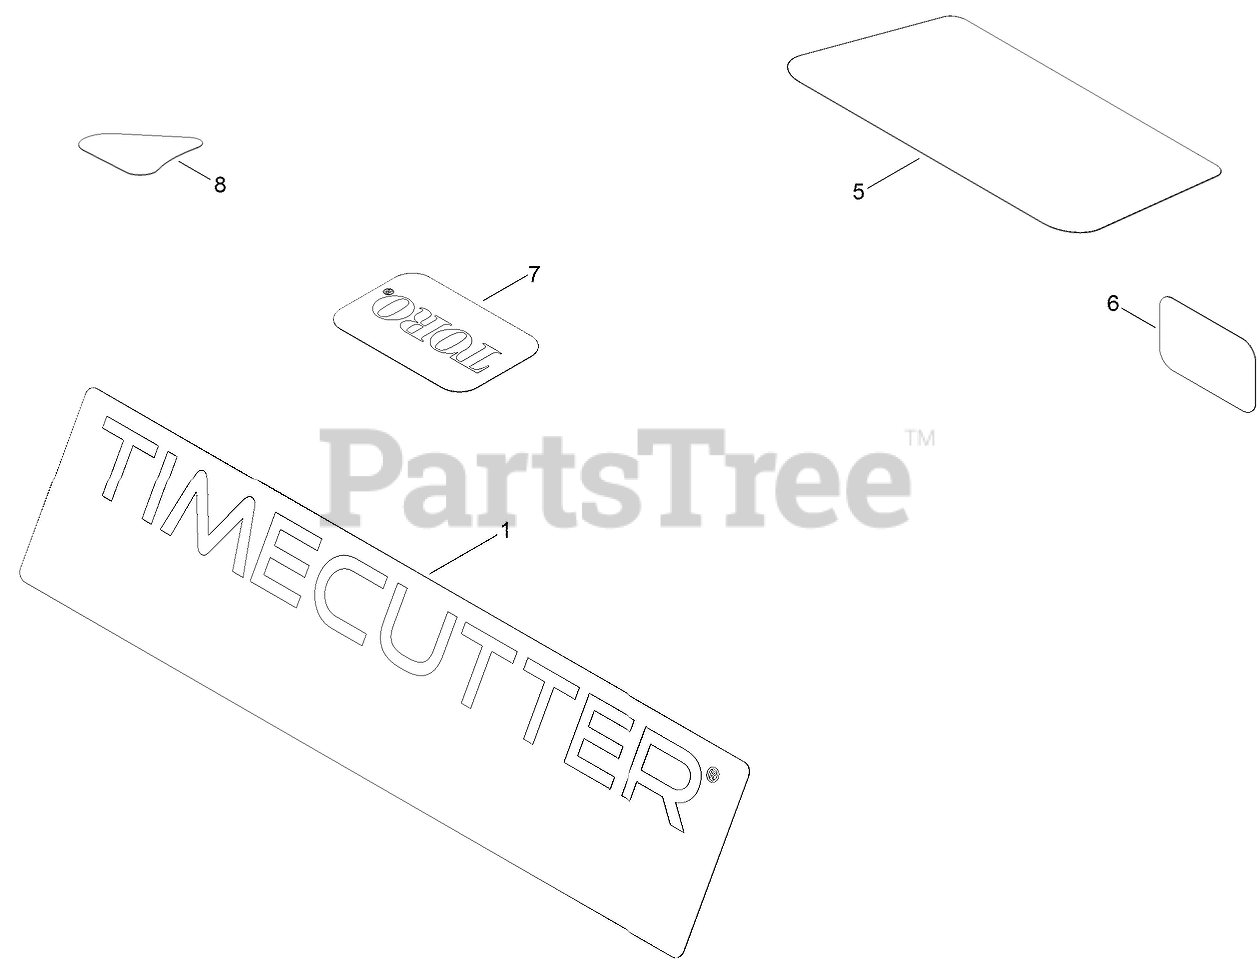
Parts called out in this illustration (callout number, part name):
1	DECAL-TIMECUTTER
5	DECAL-ENGINE
6	PLACARD-INTAKE
8	DECAL-DRAIN, OIL
